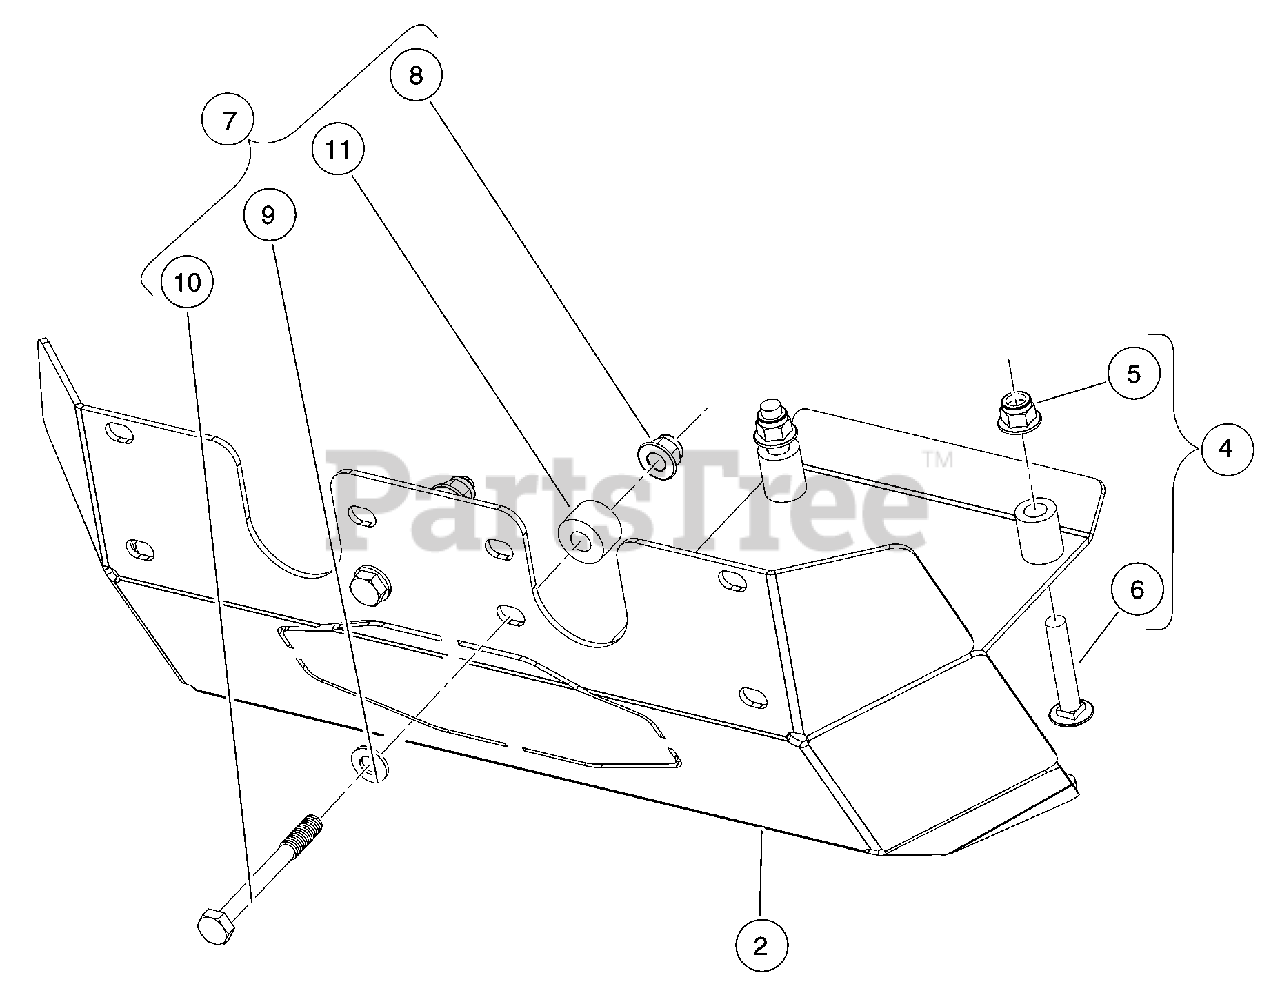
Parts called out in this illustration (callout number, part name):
1	Kit, Skidplate, Front, Steel
2	Skid Plate, Front, Steel
3	Instructions, Front Skidplate
4	Kit, Hardware, Skidplate, Front, A
5	Nut Flg M10 X 15 Nylon
6	Bolt, Carriage, M10x15x55
7	Kit, Hardware, Skidplate, Front, B
8	Nut Flg M10 X 15 Nylon
9	Washer, Hard, M10, Zn-Ni/Blk
10	Bolt, M10 X 150 X 90, Loctite
11	Spacer, 17mm Long, Skidplate
